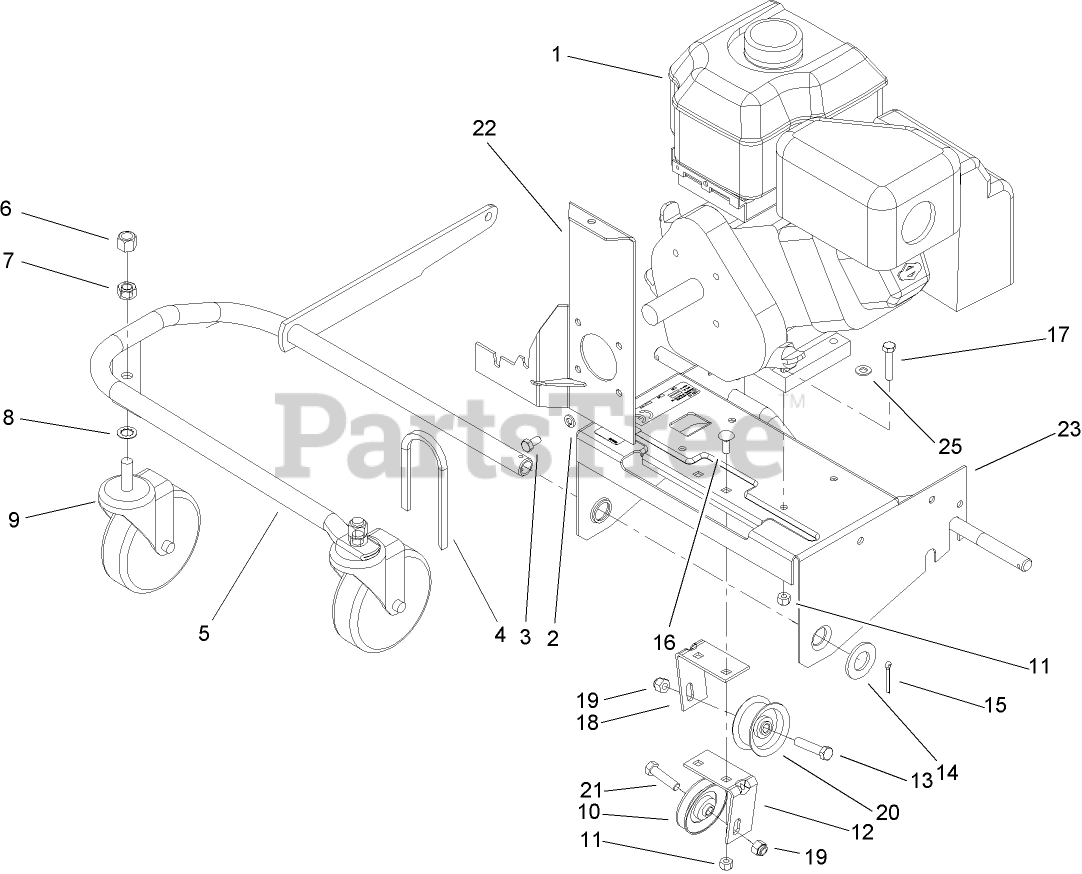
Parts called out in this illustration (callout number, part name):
1	Loose Parts Package
2	WASHER-LOCK
3	SCREW-HH
4	V BELT
5	FRONT WHEEL SUPPORT ASM
6	NUT-LOCK, NI
7	NUT-HH
8	WASHER-LOCK/INT
9	CASTER
10	PULLEY-IDLER
11	NUT-LOCK, NI
12	BRACKET-IDLER MOUNT, LH
13	SCREW-HH
14	WASHER-FLAT
15	PIN-COTTER
16	BOLT-CARR
17	SCREW-HH
18	BRACKET-IDLER MOUNT, RH
19	NUT-LOCK, NI
20	PULLEY-IDLER
21	SCREW-HH
22	STABALIZER BRACKET ASM
23	PLATE-ENGINE
25	WASHER-PLAIN
